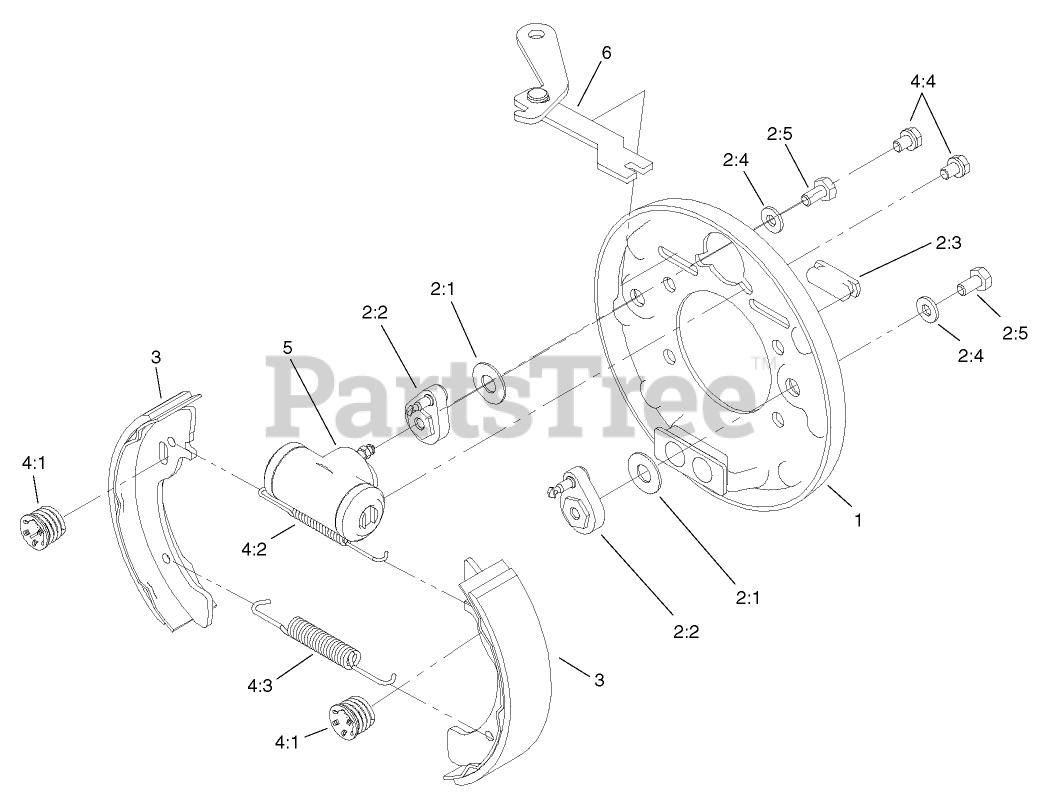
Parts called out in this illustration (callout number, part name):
1	BACKING PLATE ASM
2	ADJUSTER KIT
2:1	WASHER-BELLVILLE
2:2	ADJUSTER LEVER ASM
2:3	COVER-DUST
2:4	Washer
2:5	Bolt
3	SHOE AND LINING KIT
4	HARDWARE KIT
4:1	SHOE HOLD DOWN SPRING ASM
4:2	SPRING-UPPER
4:3	SPRING-LOWER
4:4	Loose Parts Package
5	WHEEL CYLINDER ASM
6	RH PARK BRAKE LEVER ASM
